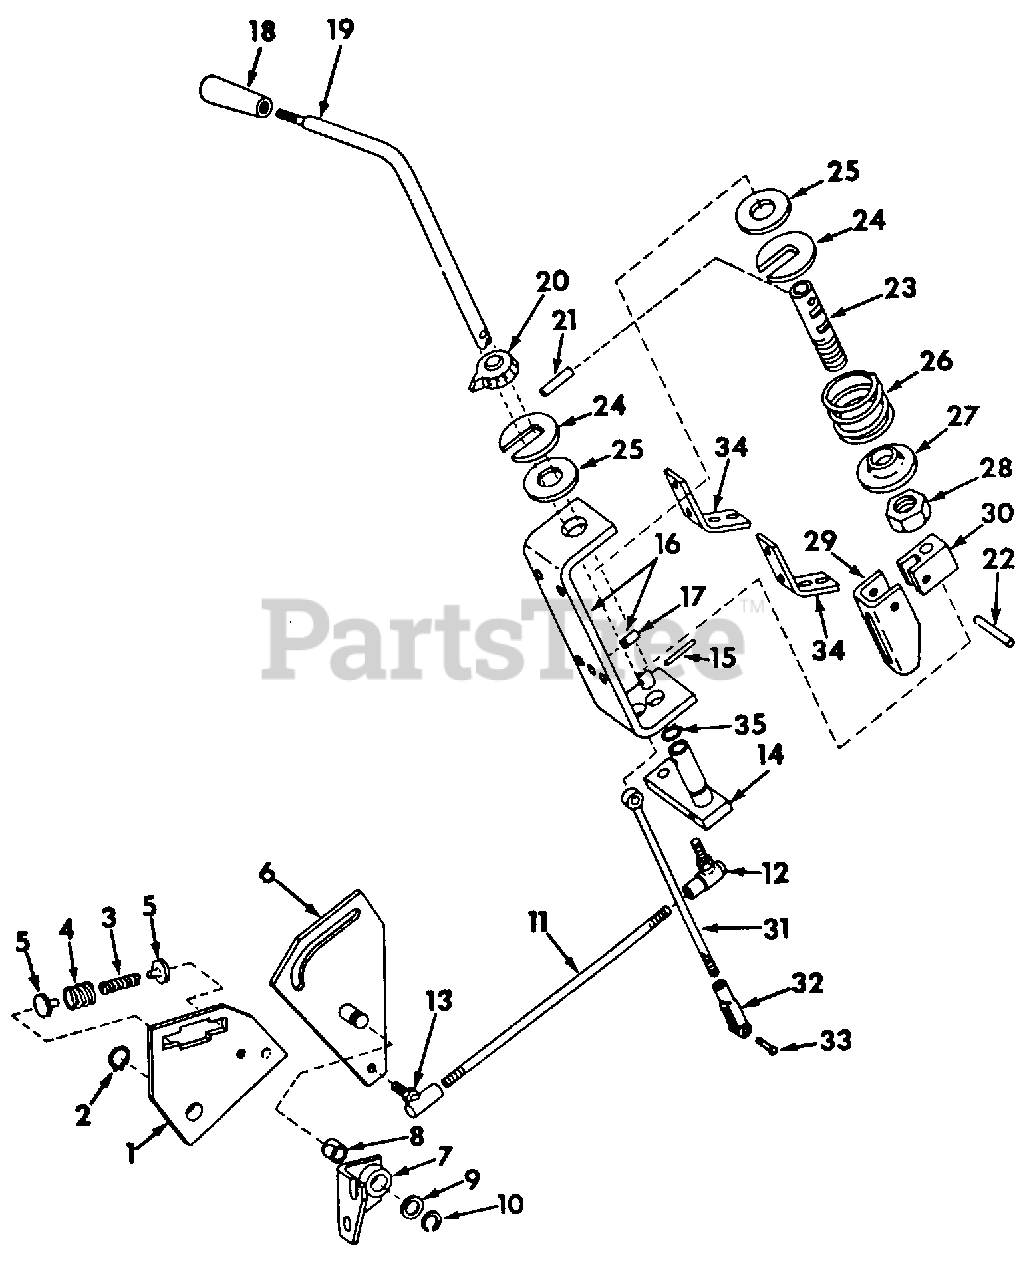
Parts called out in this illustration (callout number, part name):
1	Plate Assy, Damper Spring
2	Ring, Damper Plate Retaining
3	Spring, Damper Light
4	Spring, Damper Heavy
5	Pin, Damper Spring Guide
6	Cam Assy, Speed Control
7	Bracket Assy, Cam Pivot
8	Bushing, Cam Pivot
9	Washer, Cam Retaining
10	Ring, Cam Retaining
11	Rod, Speed Control Connection
12	Joint, 5/16-24 X 1-1/2 C-Z RH Thd Ball
13	Joint, 5/16-24 X 1-1/2 LH Thd Ball
14	Lever Assy, Speed Control
15	Pin, 1/4 X 1-3/4 Dowel
16	Bracket Assy, Hand Control Mounting
17	Pin, 1/4 X 1/2 Dowel
18	Grip, Speed Control Rod
19	Rod, Speed Control
20	Indicator, Speed Position
21	Pin, 1/4 X 1-1/4 Dowel
22	Pin, 1/4 X 1-1/2 Hv Coiled Spring
23	Shaft, Frictional Adjusting Column
24	Retainer, Spring
25	Washer, Frictional Disc
26	Spring, Frictional
27	Washer, Frictional Spring Guide
28	Nut, 7/8-14 Esna Stop
29	Channel, Speed Control Centering Cam
30	Swivel, Cam Centering Actuator
31	Rod Assy, Centering Cam Actuating
32	Yoke, 1/4-28 X 2 Light Adj Rod End
33	Pin, 1/4 X 51/64 C-Z Rod End
34	Brace, Control Bracket Reinforcement
35	Ring, Lever Retaining
